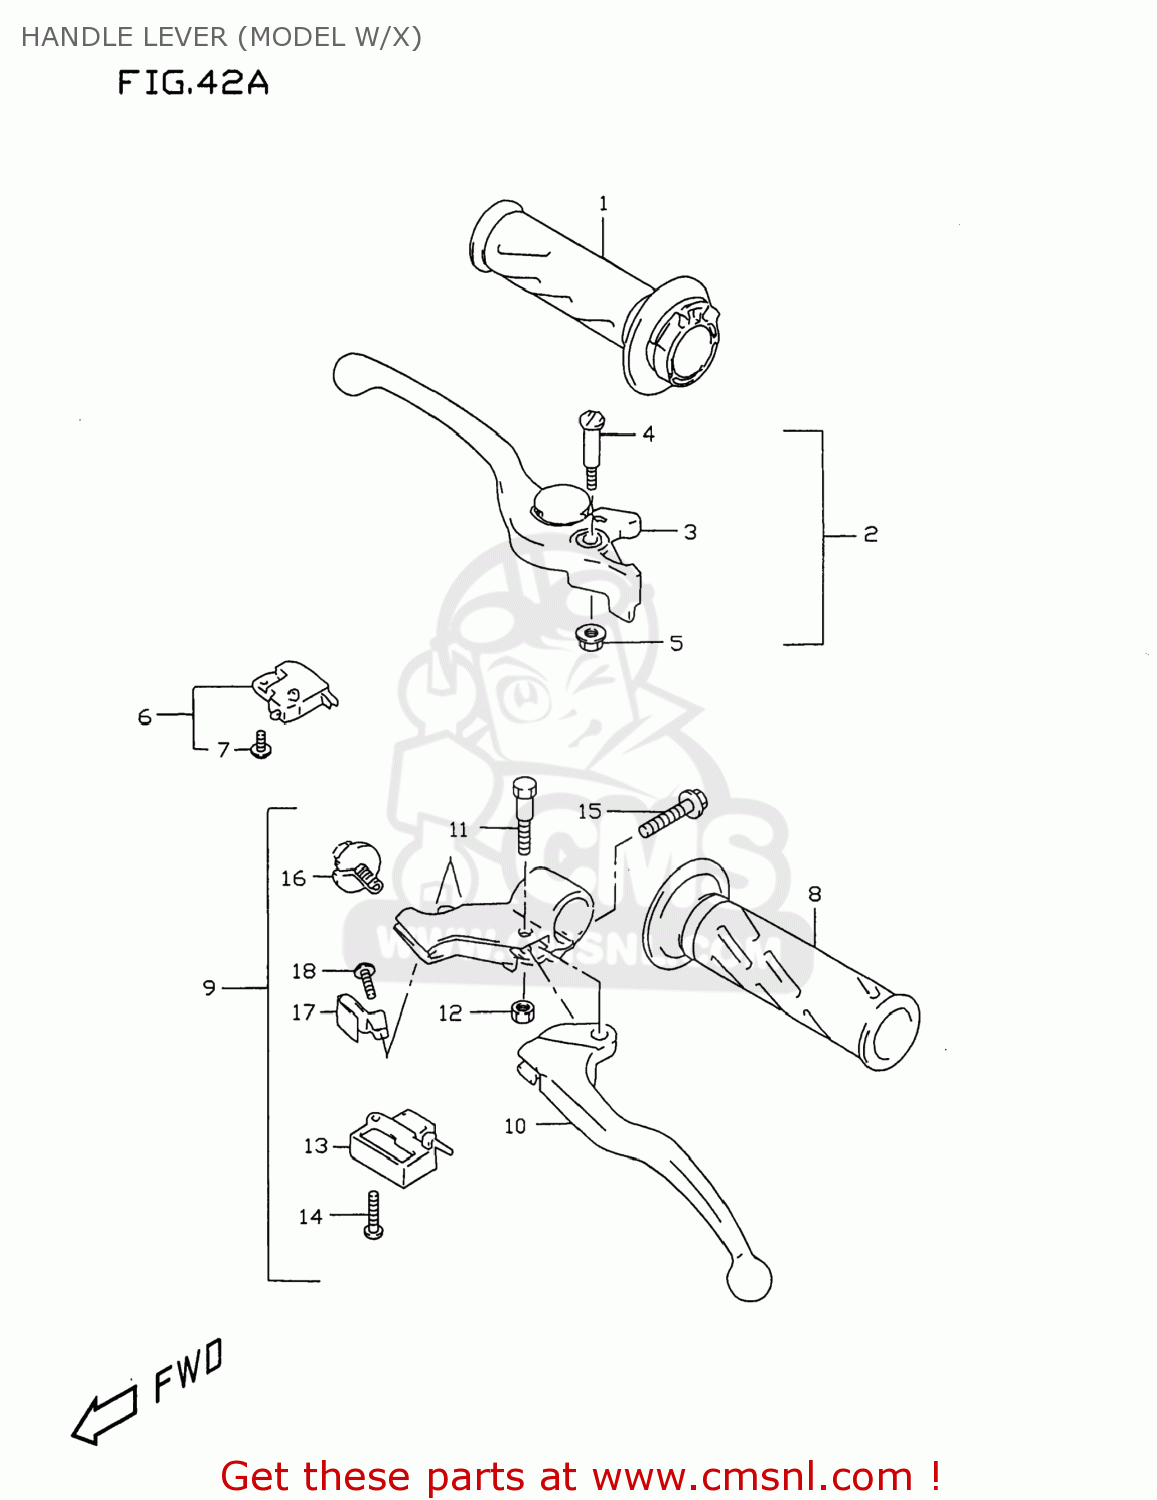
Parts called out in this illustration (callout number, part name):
1	GRIP,THROTTLE
2	LEVER ASSY,BRAKE
3	LEVER ASSY,ADJUST
4	BOLT,LEVER PIVOT
5	NUT
6	SWITCH ASSEMBLY,STOP
7	SCREW
8	GRIP,LEFT
9	LEVER ASSEMBLY,CLUTCH
10	LEVER,CLUTCH
11	BOLT,LEVER SET
12	NUT
13	SWITCH,CLUTCH
14	SCREW
15	SCREW
16	NUT,CABLE ADJUSTER
17	SPRING,ADJUST
18	SCREW,SPRING
